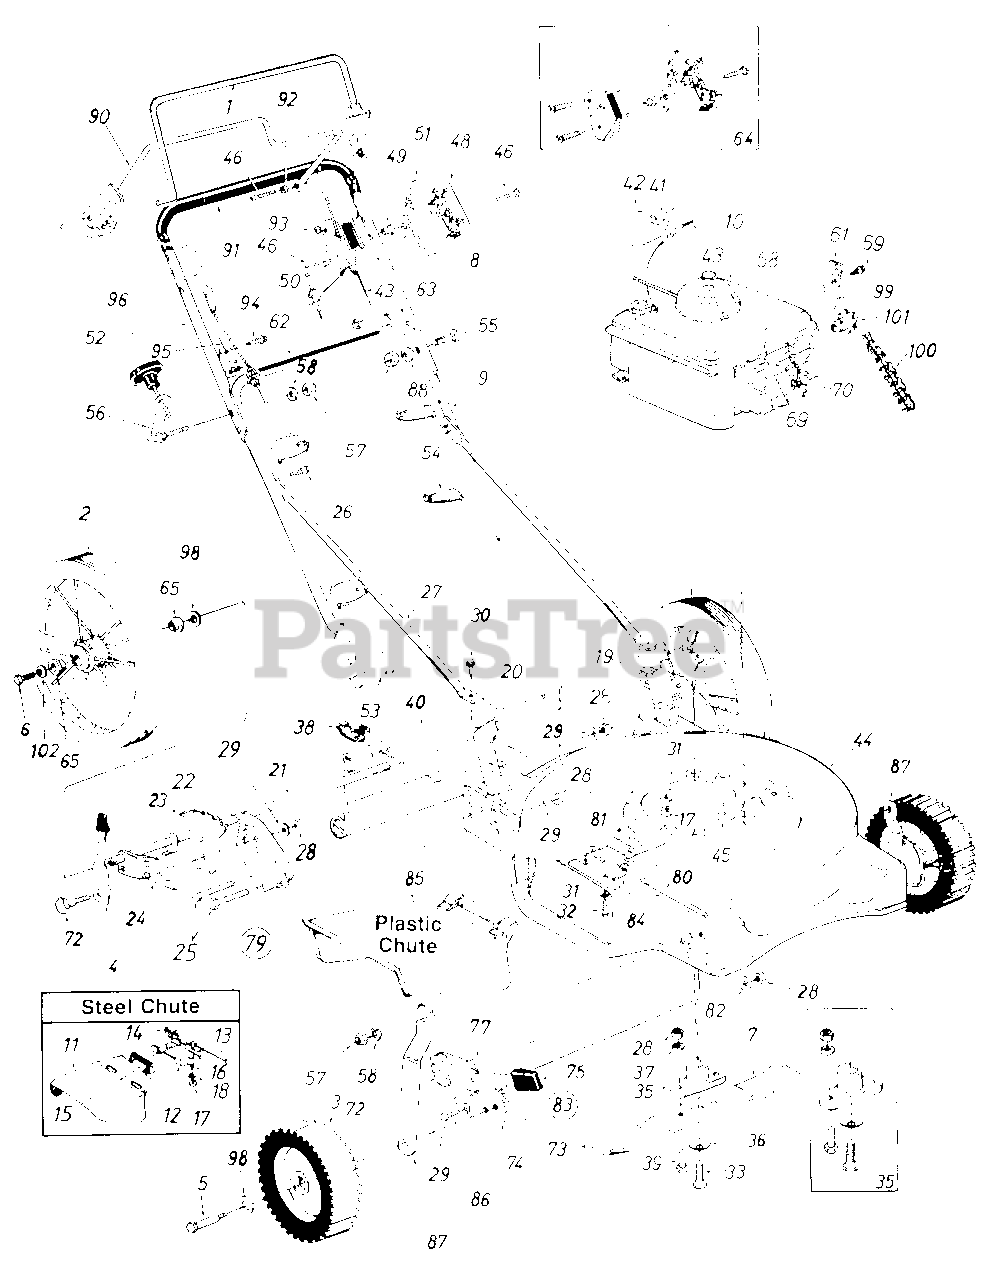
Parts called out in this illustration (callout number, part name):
1	Control Handle Ass'y.
2	Rear Wheel Ass'y. Comp. 14.0 x 1.75
3	Front Wheel Ass'y. Comp. 8.0 x 1.75
4	Spring Lever Ass'y. w/Knob
5	Front Axle Bolt
6	Hex Bolt 1/4-20 x .62" Lg.
7	22" Blade
8	Throttle Wire-53" Lg.
9	Lower Handle
10	Engine
11	Chute Deflector Assy. Comp.
12	Adapter Plate
13	Pivot Pin
14	Push Nut 1/4" Rod
15	Torsion Spring
16	Hex Bolt 1/4-20 x .50" Lg.
17	Hex Nut 1/4-20 Thd.
18	L-Wash. 1/4" I.D.*
19	Handle Mount Brkt.-L.H.
20	Handle Mount Brkt.-R.H.
21	Rear Axle Ass'y.
22	Mounting Plate
23	Height Adj. Plate
24	Order Height Adj. Ass'y. Comp.
25	Hex Bolt 3/8-16 x .75" Lg.
26	Hex Wash. AB-Tap Scr. 5/16 x .75" Lg.
27	Strut Bar 22.95" Lg.
28	Hex Nut 3/8-16 Thd.
29	Bell-Wash. .400" I.D. x .88"
30	Hex Bolt 1/4-20 x .62" Lg.
31	Bell-Wash. .265" I.D. x .75" O.D.
32	Hex Wash. Hd. Tap Scr. 1/4-20 x .5" Lg.
33	Hex Bolt 3/8-24 x 1.5" Lg. (Grade 5)
35	Blade Adapter Kit
36	Bell-Wash. .39" I.D.
37	L-Wash. 3/8" I.D.
38	Hinge Clip
39	Hex Bolt 3/8-16 x 1" Lg.
40	Rear Flap Ass'y.
41	Cable Bracket
42	Pop Rivet .156 Dia. x .379
43	Control Cable-39"
44	22" Deck Ass'y.
45	Hex Wash. Hd. TT-Tap Scr. 3/8-16 x 1.00" Lg.
46	Truss Mach. 'B"-Tap Scr. #12 x 1.50" Lg.
48	Control Panel Half
49	Control Disc Pin
50	Clutch Panel Half
51	Throttle Control Lever
52	Upper Handle
53	Intern. Cot. Pin 5/16" Dia.
54	Cable Tie
55	Curved Carriage Bolt 5/16-18 x 1.38" Lg.
56	Rope Guide Bolt
57	Hex Nut 5/16-18 Thd.
58	L-Wash. 5/16" I.D.
59	Hex B-Tap Scr. #10 x .38" Lg.
61	Casing Clamp
62	Instruction Label-Handle
63	Control Label-Throttle
64	Control Housing Comp.
65	Flange Bearing
68	Casing Clamp
69	Hex B-Tap Scr. #10 x .62" Lg.
70	Spark Plug Boot
72	Shoulder Bolt .50" Dia.
73	Spring Lever
74	Pivot Bar-R.H.
75	Spring Lever Knob
77	Index Plate
79	Rear Height Adj. Ass'y. Comp.-R.H.
80	Hinge Pin
81	Torsion Spring
82	Bell-Wash. .39" I.D. x 1.38"
84	Adapter Plate
85	Chute Deflector Ass y. Comp.
86	Hex AB-Tap Scr. 1/4 x .62"
87	Link
88	Bell-Wash. 5/16" I.D.
90	S.P. Bail Ass'y.
92	Spacer .23" I.D. x .3" O.D.
93	Spr.-Wash..206" I.D.
94	Hex Wash. AB-Tap Scr. 5/16 x.75" Lg.
95	Cable Mounting Brkt.
96	Drive Cable
98	Fl-Wash. .531" I.D. x .93"
99	Spring Pin 3116" Dia.
100	#48 Chain 1/2" Pitch 50 Links (Endless)
101	10 Tooth Sprocket Ass'y.
102	Bell-Wash. .265" I.D. x .75" O.D.
